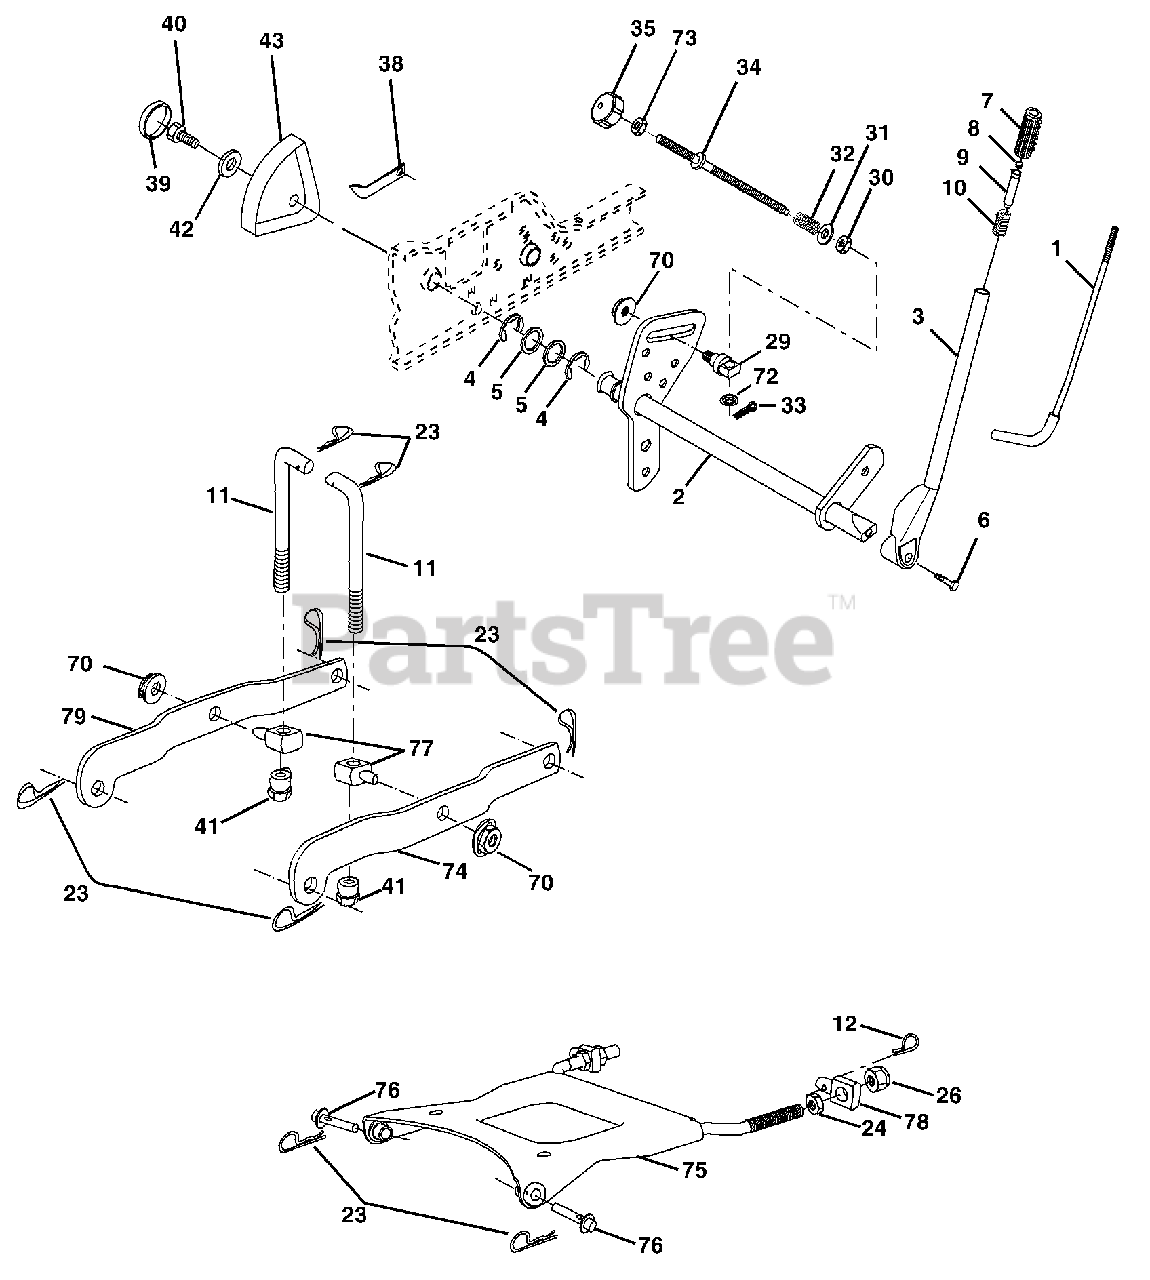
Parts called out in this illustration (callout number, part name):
1	Rod Asm., Lever
2	Shaft Asm., Lift Vgt
3	Lever Asm., Lift Rh
4	E-Ring Truarc #5133-87
5	Washer 29/32 x 1-1/4 x 16 Ga.
6	Bolt, Fin Hex 3/8-16 x 1-1/2
7	Grip, Handle Fluted
8	Plunger, Button
9	Plunger Lever Lift
10	Spring
11	Link Lift
12	Retainer Spring
23	Retainer, Spring
24	Nut, Jam Hex 1/2-13 unc
26	Nut lock 1/2-13 unc
29	Trunnion, Infin Height
30	Nut, Special
31	Washer 13/32 x 5/8 x 16 Ga.
32	Spring, Compression Inf Hgt
33	Pin, Cotter 3/32 x 1/2
34	Rod, Adj Lift
35	Knob, Inf 3/8-16 unc
38	Pointer, Height Indicator
39	Plug, Hole
40	Screw Hex Wsh 5/16-18 x 1
41	Nut, Lift Link 7/16-20
42	Washer 11/32 x 1-1/2 x 10 Ga.
43	Scale, Indicator Height
70	Nut Hex Flange Lock
72	Nut Push Phos & Oil
73	Nut Hex Jam 3/8-16 unc
74	Arm Susp. Rear RH
75	Plate Asm. Susp. Front
76	Pin, Flange
77	Trunnion Susp. Arm
78	Trunnion Susp. Front
79	Arm, susp. R LH
